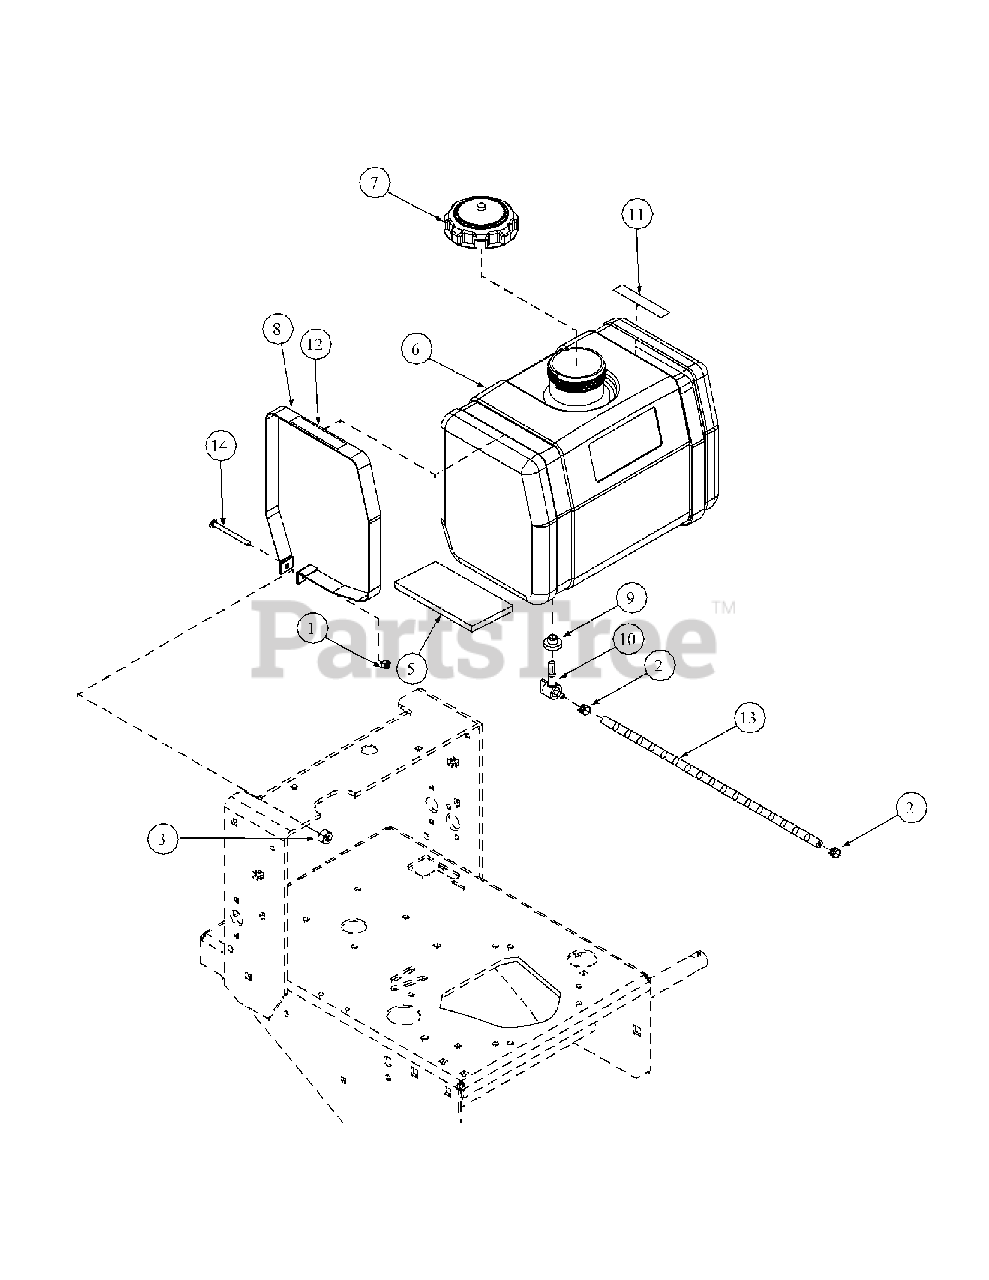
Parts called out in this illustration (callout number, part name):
1	Lock Nut, Nylon Insert, 1/4-20
2	Uni-Clamp
3	Spacer
5	Rubber Stop Pad
6	Fuel Tank
7	Fuel Cap, 3.5
8	Fuel Tank Strap
9	Grommet Fuel Tank
10	Shut Off Fuel Tank
11	Label, Mower Warning Turn Off Engine
12	Label, Mower Instruction, Fuel Valve
13	Hose Fuel, 18"
14	Carriage Bolt, 1/4-20 x 3.00
